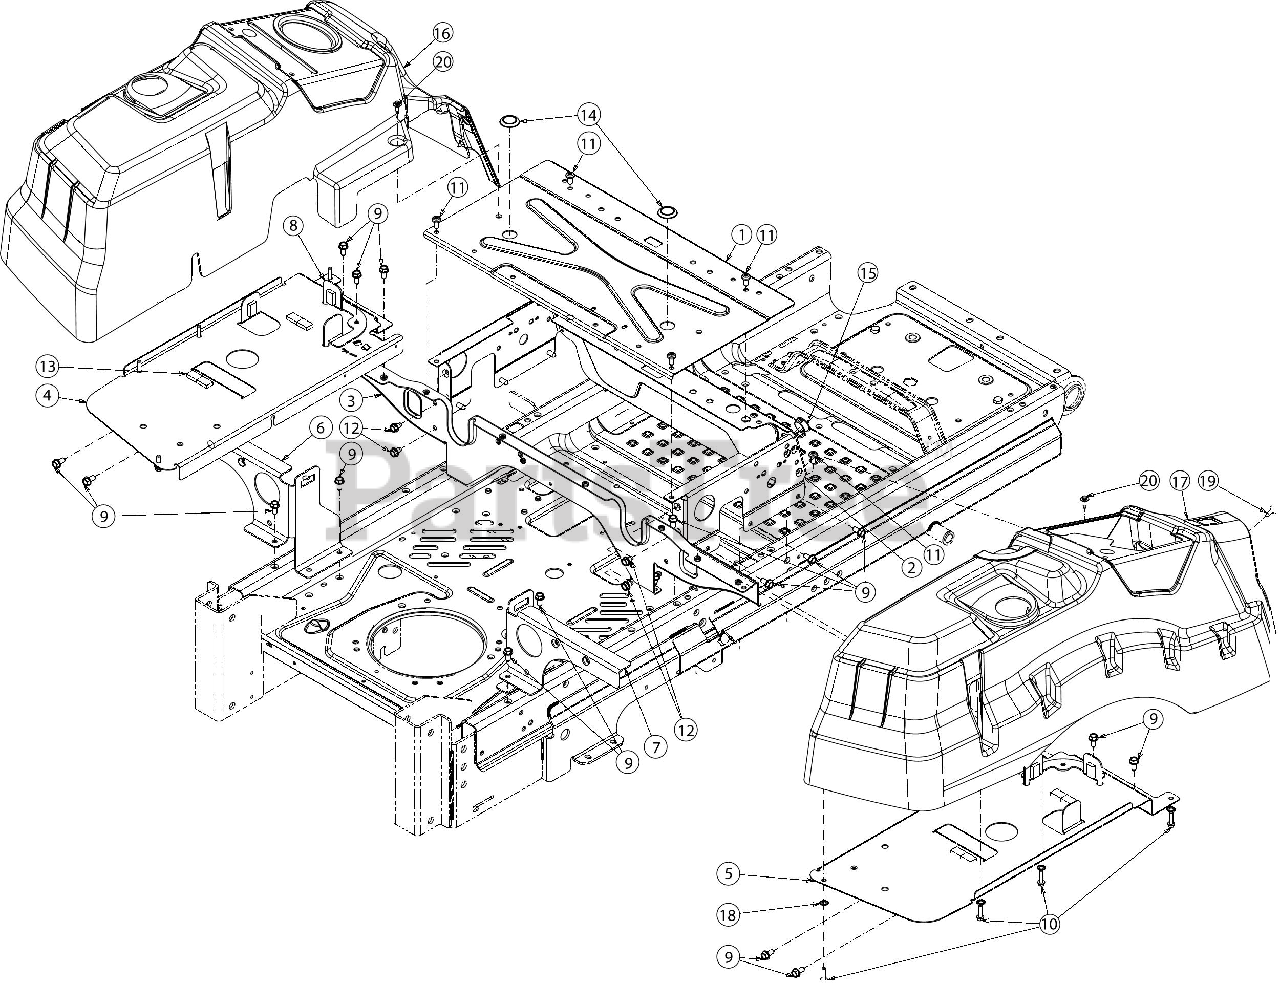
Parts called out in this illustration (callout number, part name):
1	SEATBOX TOP PLATE
2	SEAT FRAME
3	REAR SEATBOX BRACE
4	TANK SUPPORT PLATE (LH)
5	TANK SUPPORT PLATE (RH)
6	REAR BRACKET SUPPORT (LH)
7	REAR BRACKET SUPPORT (RH)
8	REAR TANK BRACKET
9	SCREW 5/16-18 x .750
10	SCREW 5/16-14 x 1
11	SCREW 5/16-18 x .750
12	SCREW 5/16-18 x .500
13	FOAM TAPE .625 WIDE x .25 THK BULK
15	PLASTIC PLUG
16	CONSOLE (LH) 2.25" CAP
17	CONSOLE (RH) 2.25" CAP
19	TORX SHOULDER SCREW 1/4-20
20	SHOULDER SCREW M6-1 .368 X.115
